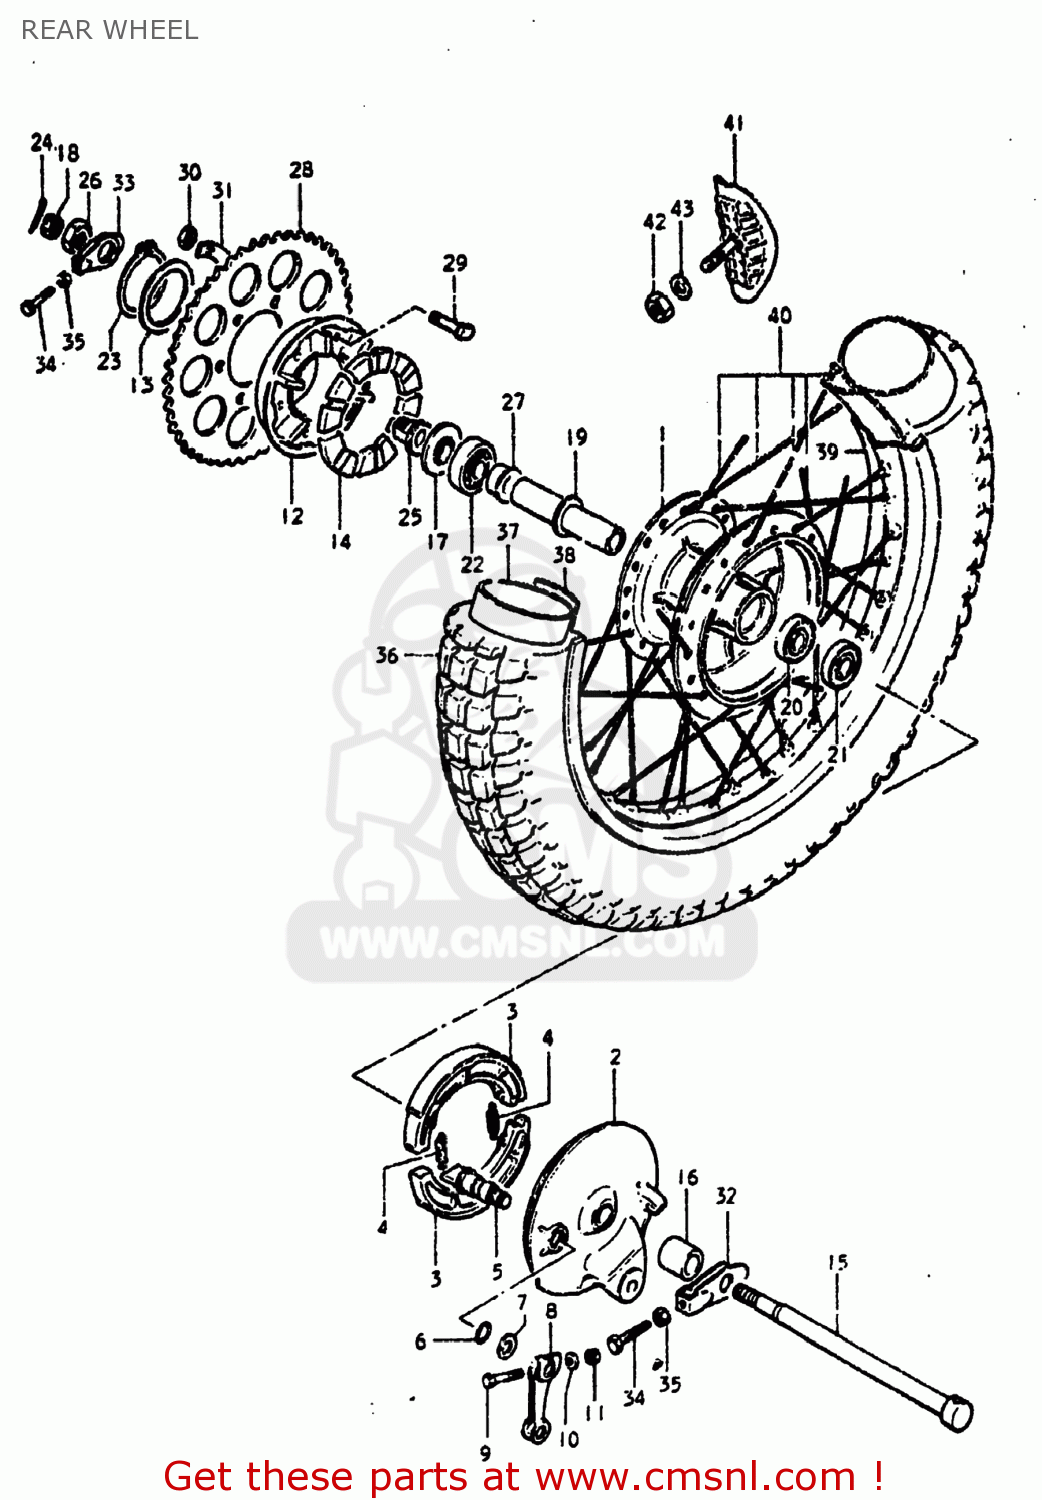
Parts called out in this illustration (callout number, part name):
1	DRUM,REAR HUB
2	PANEL,REAR HUB
3	SHOE,BRAKE (MCA)
4	SPRING
5	CAM,FRONT BRAKE
6	O-RING,BOSS
7	WASHER (15X24X1.6)
8	LEVER,RR BRAKE CAM
9	BOLT 6X40
10	WASHER
11	NUT
12	DRUM,REAR SPROCKET MOUNT
13	WASHER(62.5X77X1.6)
14	ABSORBER,RR WHEEL HUB SHOCK
15	AXLE,REAR
16	SPACER (15.2X26X20)
17	SPACER,REAR AXLE,RIGHT
18	NUT
19	SPACER,REAR HUB BEARING
20	BEARING, RH
21	OIL SEAL
22	BEARING
23	CIRCLIP
24	PIN 30X40
25	SPACER,REAR AXLE,LEFT
26	NUT
27	SPACER,REAR HUB BEARING
28	SPROCKET,REAR
29	BOLT(8X33.5)
30	NUT
31	WASHER
32	ADJUSTER,CHAIN
33	ADJUSTER,CHAIN,L
34	BOLT
35	NUT
36	TIRE
37	TUBE ASSEMBLY,WHEEL,INNER
38	PROTECTOR,INNER TUBE
39	RIM,WHEEL
40	SPOKE SET,RR
41	STOPPER,BEAD
42	NUT
43	WASHER
